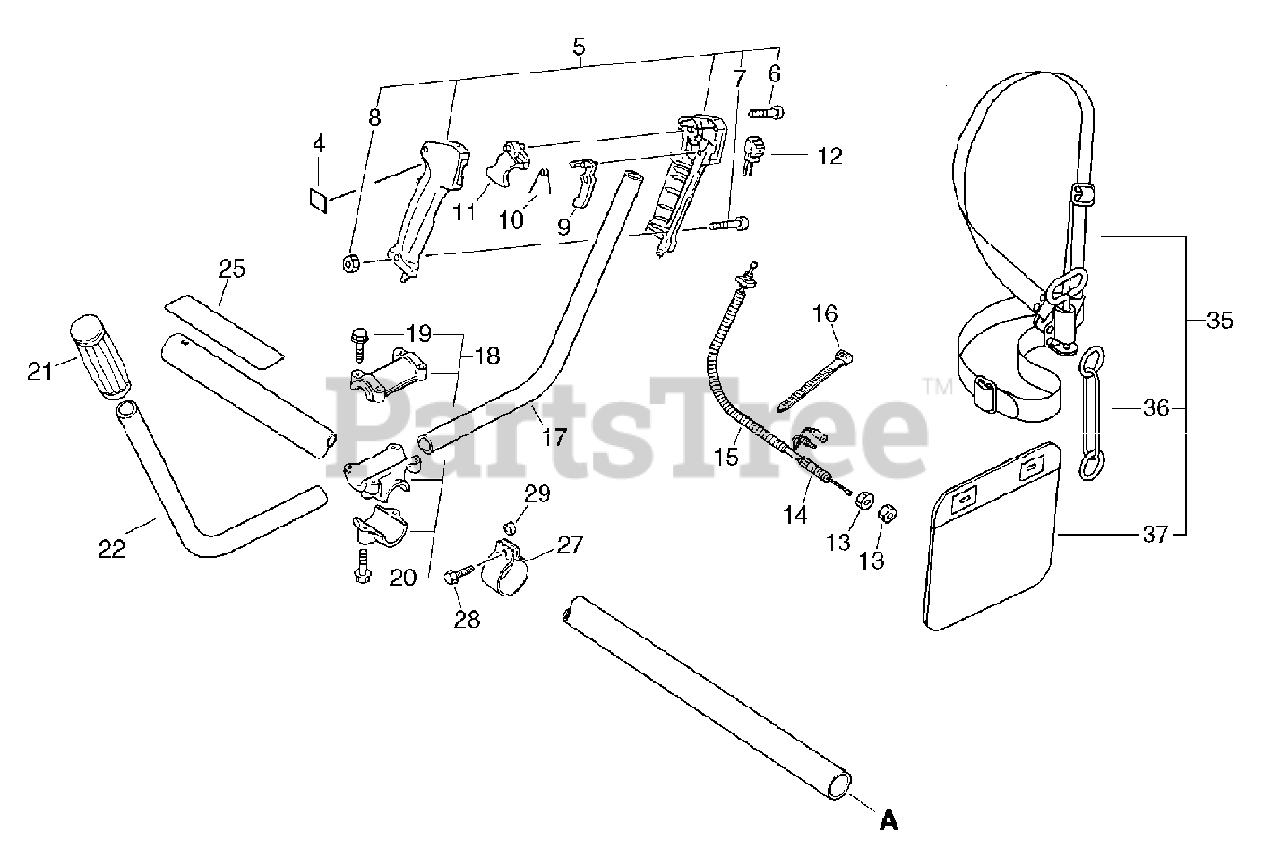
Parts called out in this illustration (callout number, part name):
4	Label, Switch
5	Grip Assy, f-Handle
6	Screw 3*25
7	Screw 5*30
8	Nut 5
9	Lockout, Throttle
10	Spring, Thr. Lock
11	Control, Throttle
12	Switch, Ignition
14	Wire, Throttle
15	Tube
17	Handle, Front
18	Fixture,Asy Handle
19	Bolt 5*25 (W/W,SW)
20	Bolt 6*30 (W/W,SW)
21	Grip, Handle
22	Handle, Left (SL)
25	Label,Caution
28	Bolt 5*18
35	Harness Asy,Shoulder
36	Link
37	Pad,Waist
